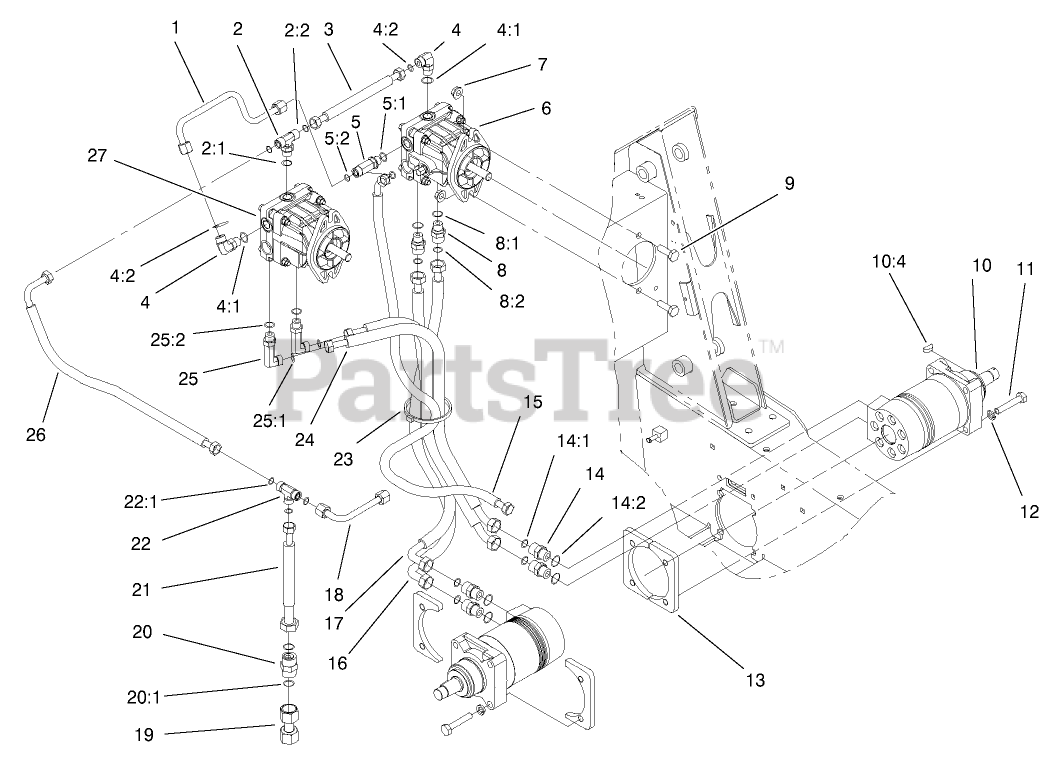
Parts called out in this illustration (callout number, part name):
1	TUBE-HYD
2	FITTING-HYD, TEE
2:1	O-RING
2:2	O-RING
3	HYD HOSE ASM
4	FITTING-ELBOW-90 DEG
4:1	O-RING
4:2	O-RING
5	FITTING-TEE
5:1	O-RING
5:2	O-RING
6	PUMP-HYD, LH
7	NUT-HF
8	FITTING-STR
8:1	O-RING
8:2	O-RING
9	SCREW-HH
10	MOTOR-WHEEL, HYD
10:4	KEY-WOODRUFF
11	SCREW-HH
12	WASHER-LOCK
13	PLATE-MOUNTING
14	FITTING-STRAIGHT
14:1	O-RING
14:2	O-RING
15	HOSE-HYD
16	HYD HOSE ASM
17	HYD HOSE ASM
18	HYD TUBE ASM
19	HYD TUBE ASM
20	HYD CHECK VALVE ASM
20:1	O-RING
21	HYD HOSE ASM
22	ADAPTER
22:1	O-RING
23	TIE-CABLE
24	HOSE-HYD
25	FITTING-ELBOW, 90 DEG
25:1	O-RING
25:2	O-RING
26	HYD HOSE ASM
27	PUMP-HYD, RH
